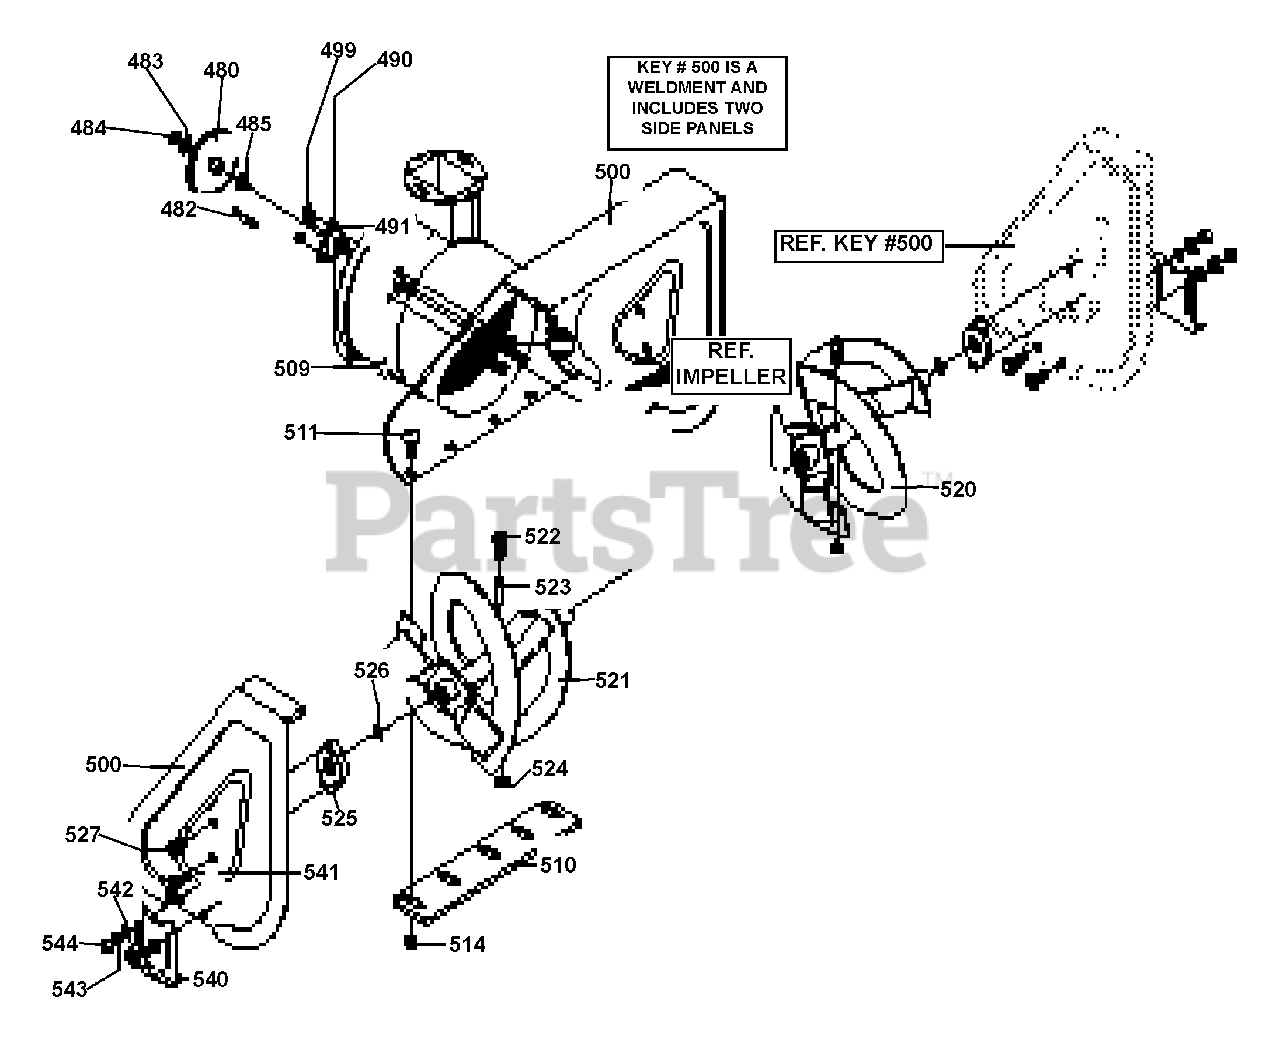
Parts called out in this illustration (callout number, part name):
480	PULLEY, V4L 8.40 OD
482	KEY, SQUARE
483	WASHER, FLAT .53 X1.00X.063
484	NUT, 1/2-20
485	SPACER, SLEEVE
490	RETAINER, BALL
491	BEARING, BALL
493	SCREW, 5/16-18X .75
499	NUT, 5/16-18
500	HSNG, ASSY
509	PLUG, CHRISTMAS TREE
510	BLADE, SCRAPER
511	BOLT, 5/16-18X..75 CARR.
514	NUT, 5/16-18 HXWDFLLK
520	AUGER, ASSY LH
521	AUGER, ASSY RH
522	SCREW, 1/4-20X1.75
523	SPACER, SLEEVE
524	NUT, 1/4-20 RGHXCTRLK
525	AUGER SHAFT BEARING
526	FLATWASHER 1.005X1.31X.035
527	SCREW, 5/16-18X .75
540	SKID, HEIGHT ADJUST
541	BOLT, 5/16-18X .75
542	FLATWASHER .344X.69X.065
543	WASHER, .328X.60X.09
544	NUT, 5/16-18 REGHEX
